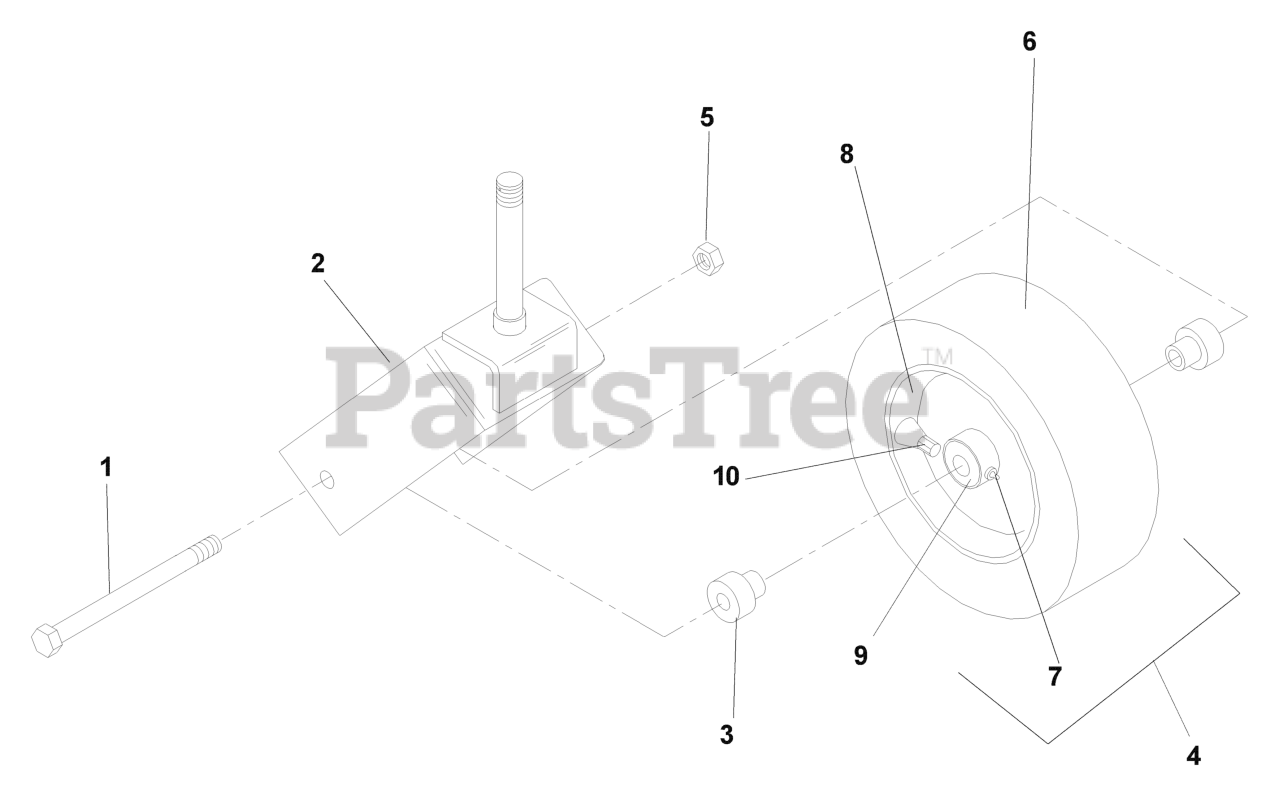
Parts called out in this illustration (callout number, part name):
1	HEX SCREW 1/2-13 X 9.5 GR5
2	CASTOR YOKE ORANGE
3	AXLE SPACER
4	FRONT TIRE ASSY
5	NUT 1/2-13 HEX NYLOC ZD
6	TIRE - SMOOTH 13X6.50-6
7	ZERK
10	VALVE STEM TR-412
